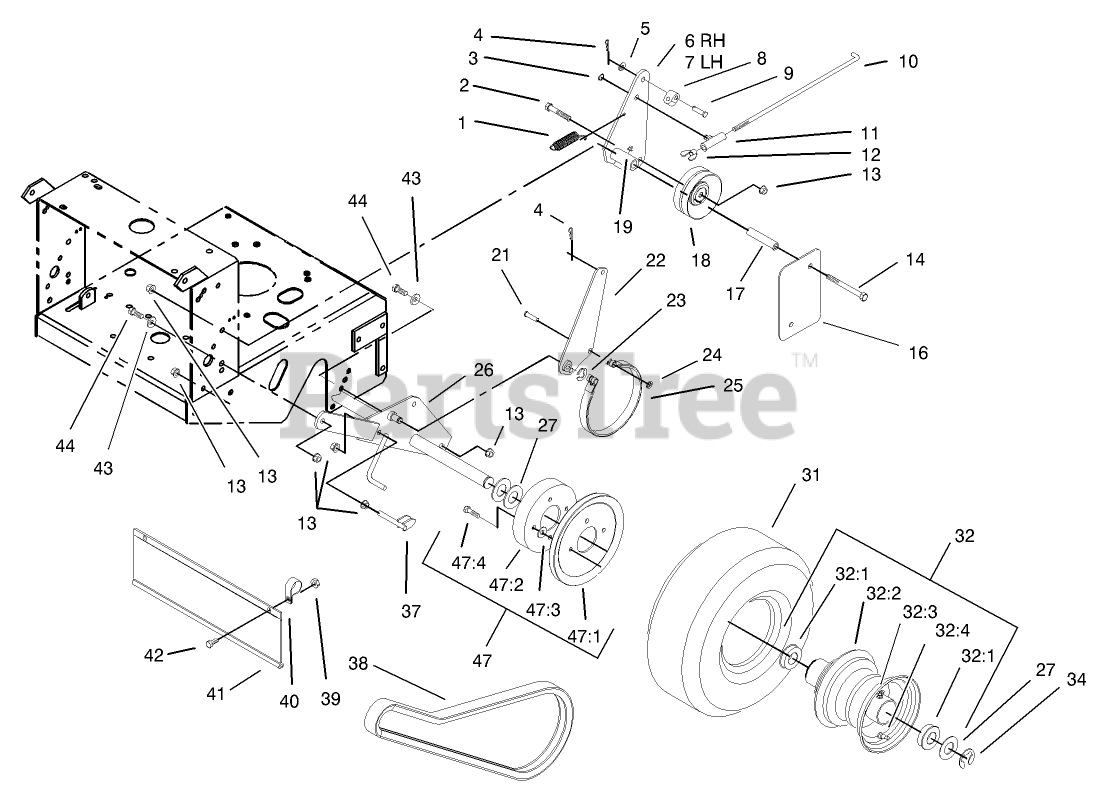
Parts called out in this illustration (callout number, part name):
1	SPRING-EXTENSION
2	SCREW-HH
3	RING-RETAINING
4	PIN-COTTER
5	WASHER-PLAIN
6	RH IDLER ARM ASM
7	LH IDLER ARM ASM
8	FITTING-ROD
9	PIN-CLEVIS
10	ROD-BRAKE
11	SWIVEL-BRAKE
12	WINGNUT-NYLOCK
13	NUT-HHF, WHIZ
14	SCREW-HH
16	SHIELD-WHEEL, DRIVE
17	SPACER-SHIELD
18	IDLER-DRIVE, WHEEL
19	FITTING-GREASE
21	PIN-CLEVIS
22	ARM-BRAKE
23	RING-RETAINING, EXTERNAL
24	NUT-PUSH
25	BAND-BRAKE
27	WASHER-SPACER
31	Tire-Turfmaster
32	WHEEL AND HUB ASM
32:1	BEARING-FLANGED
32:2	Rim ASM
32:3	Fitting-Grease
32:4	Valve Stem
34	RING-SNAP
37	SCRAPER
38	V-BELT
39	NUT-LOCK, NI
40	CLAMP-R
41	SHIELD-TRAILING
42	SCREW-HH
43	WASHER-BELLEVILLE
44	SCREW-HH
47	Drive Wheel ASM
47:1	SHEAVE-WHEEL, DRIVE
47:2	DRUM-BRAKE
47:3	SPACER-SHEAVE, WHEEL
47:4	SCREW-HH
